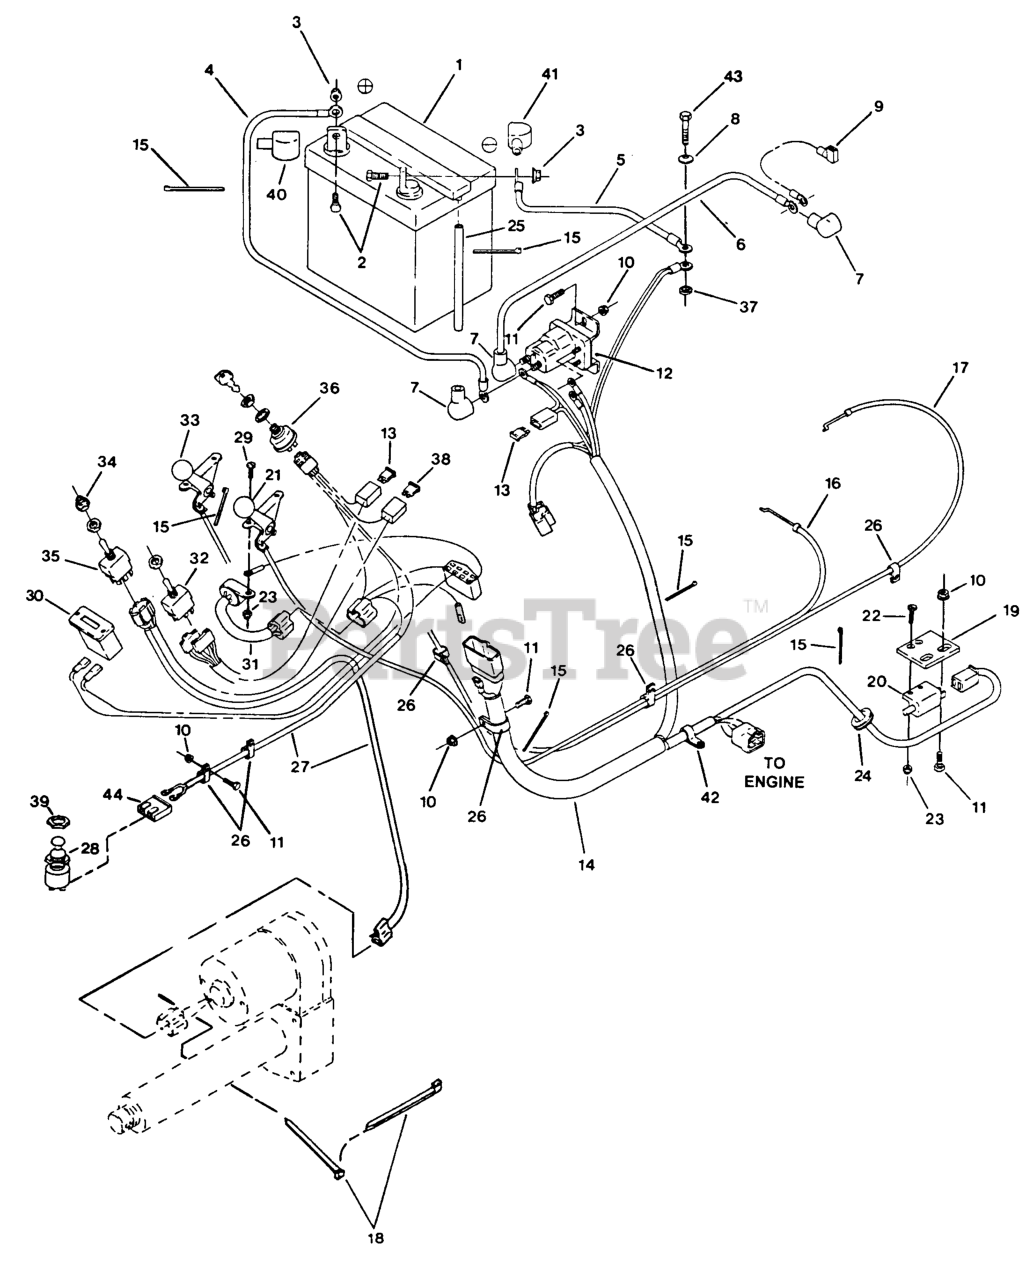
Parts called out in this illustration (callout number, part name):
1	Battery, 12v Manifold
5	WIRE-GROUND
7	INSULATOR-SOLENOID
8	WASHER-SPRING
13	FUSE-BLADE TYPE, 20 AMP
15	TIE-CABLE
18	TIE-PLASTIC
19	BRACKET,SAFETY SWITCH
20	SWITCH-OPEN, NORMALLY
21	KNOB-BALL
24	GROMMET
26	CLIP-LOOM
28	SWITCH,PUSH BUTTON
30	METER-HOUR
31	MODULE,OPC
32	SWITCH,W/TERM CLIPPD
33	KNOB-BALL, BLACK
34	BOOT-SWITCH, TOGGLE
35	SWITCH-TOGGLE, DPDT
36	SWITCH,IGNITION
38	FUSE-BLADE TYPE, 30 AMP
41	INSULATOR, BATTERY -
42	CLIP-LOOM
44	CONNECTOR,PACKARD 2 WAY
